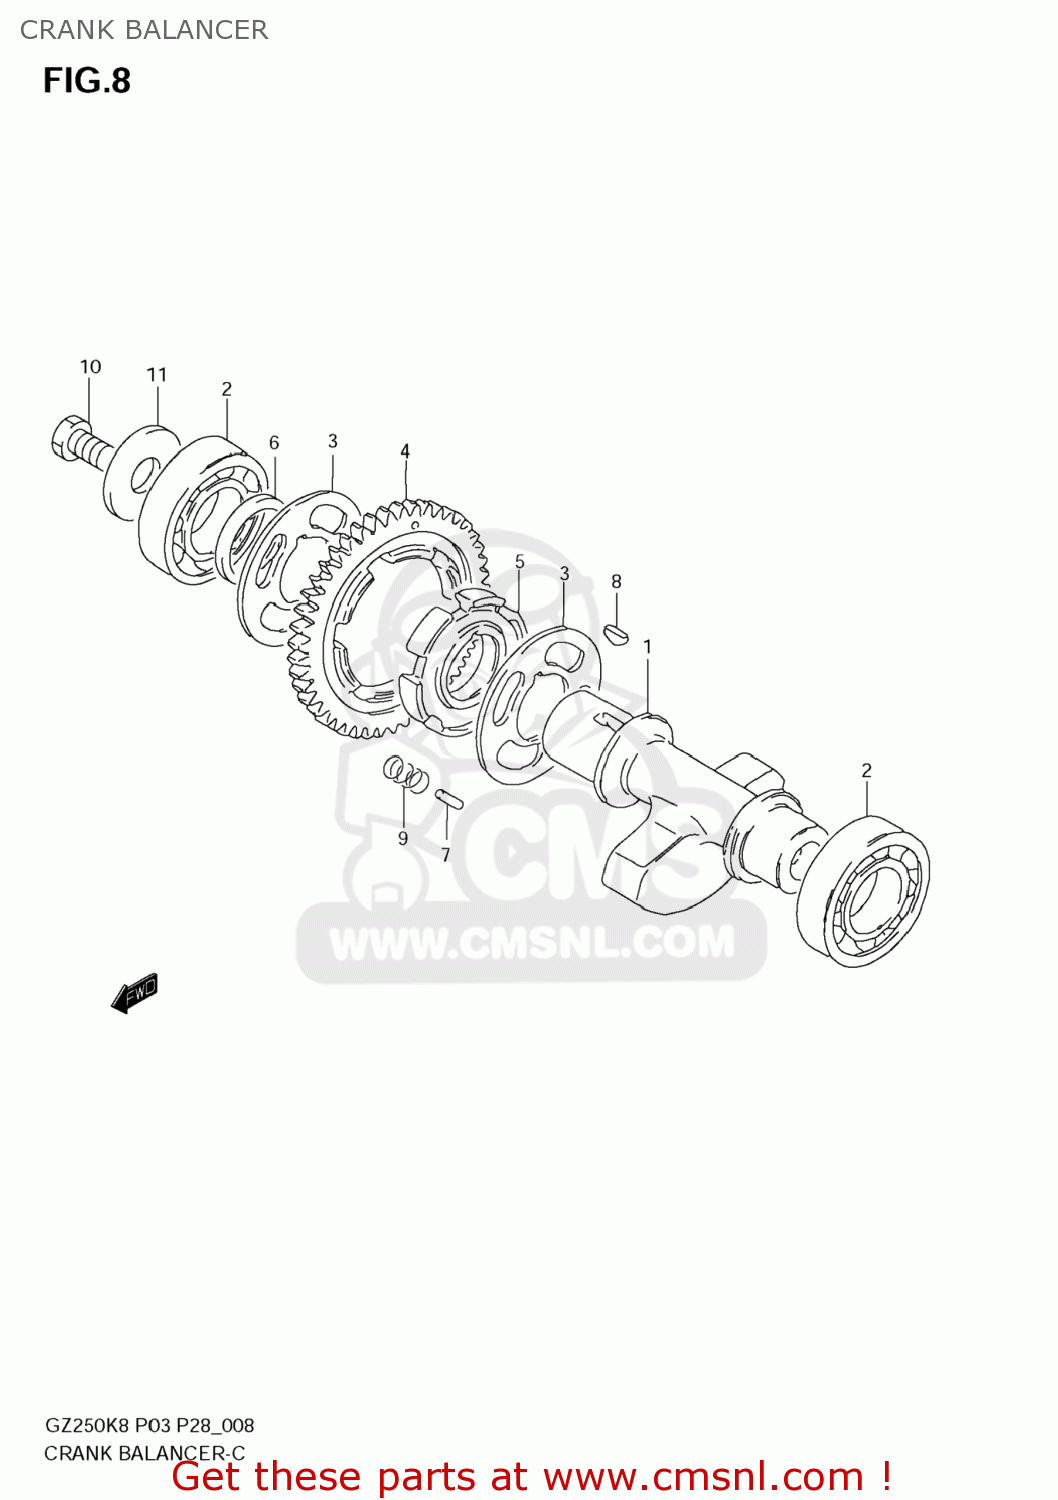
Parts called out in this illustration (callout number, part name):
1	SHAFT,CRANK BALANCER
2	BEARING(25X62X17)
3	WASHER
4	GEAR,CRANK BAL DRIVEN(NT:46)
5	RACE,CRK BAL DRIVEN GR INNER
6	SHIM(25X36X0.5)
7	PIN(4.5X9.5)
8	KEY
9	SPRING
10	BOLT
11	WASHER(12X40X2.5)
